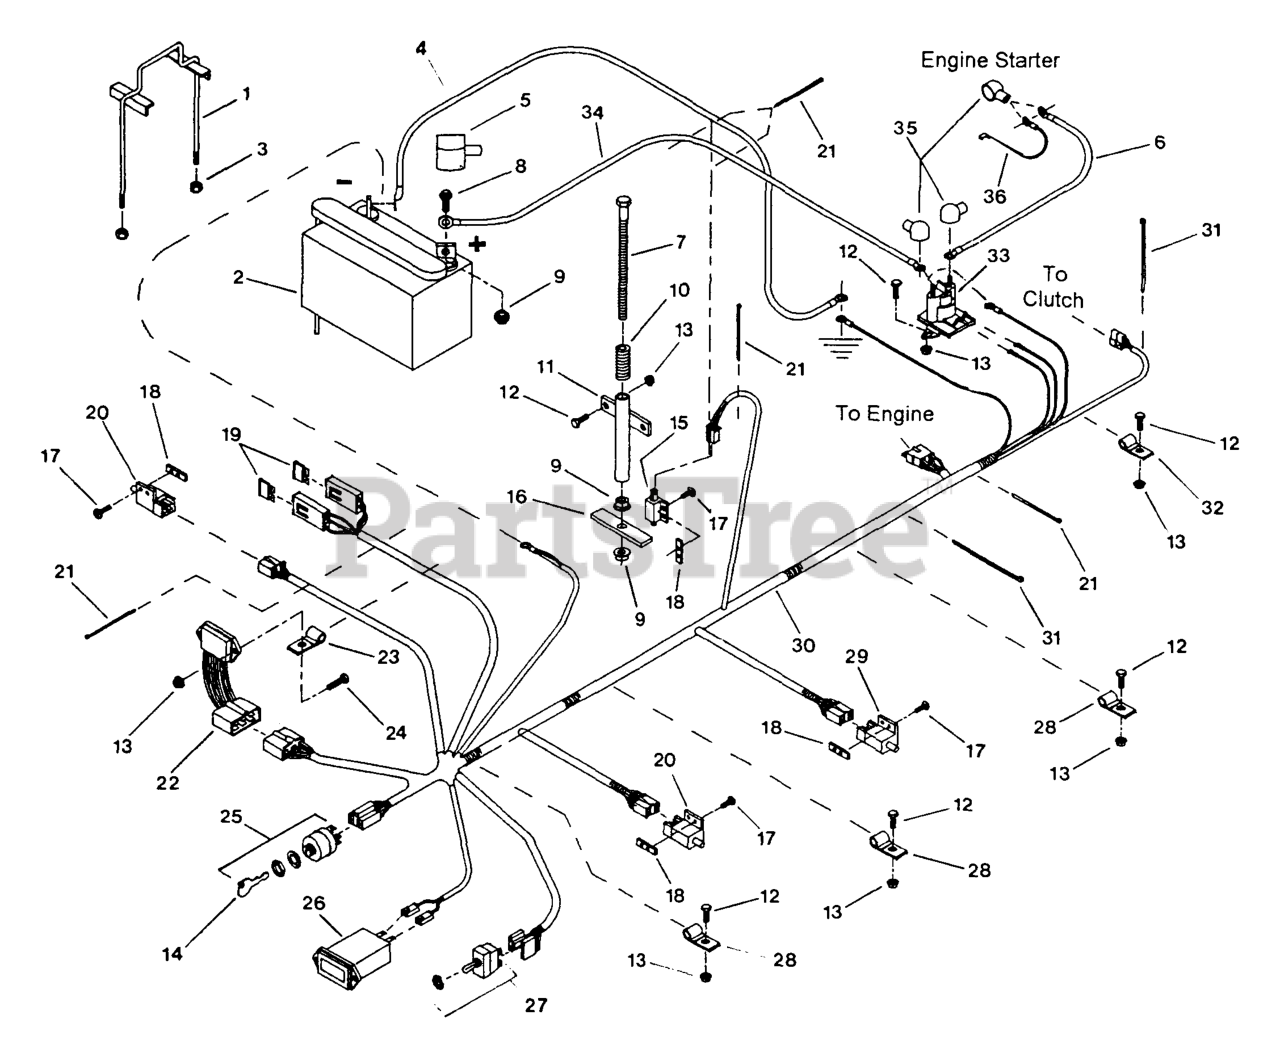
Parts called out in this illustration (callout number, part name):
2	Battery-12v Manifold
4	WIRE-GROUND
7	SCREW-HH
10	SPRING-SWITCH, SEAT
11	MOUNT-SPRING, SEAT
14	KEYS-IGNITION (SPARE PAIR
15	SWITCH-CLOSED, NORMALLY
16	PLATE-SWITCH, SEAT
18	PLATE-TAPPED
19	FUSE-BLADE TYPE, 20 AMP
21	TIE-CABLE
22	MODULE,OPC
23	CLIP-LOOM
25	SWITCH,IGNITION
26	METER-HOUR
27	SWITCH,W/TERM CLIPPD
28	CLIP-LOOM
29	SWITCH-BRAKE
31	TIE-PLASTIC
32	CLIP-LOOM
35	INSULATOR-SOLENOID
